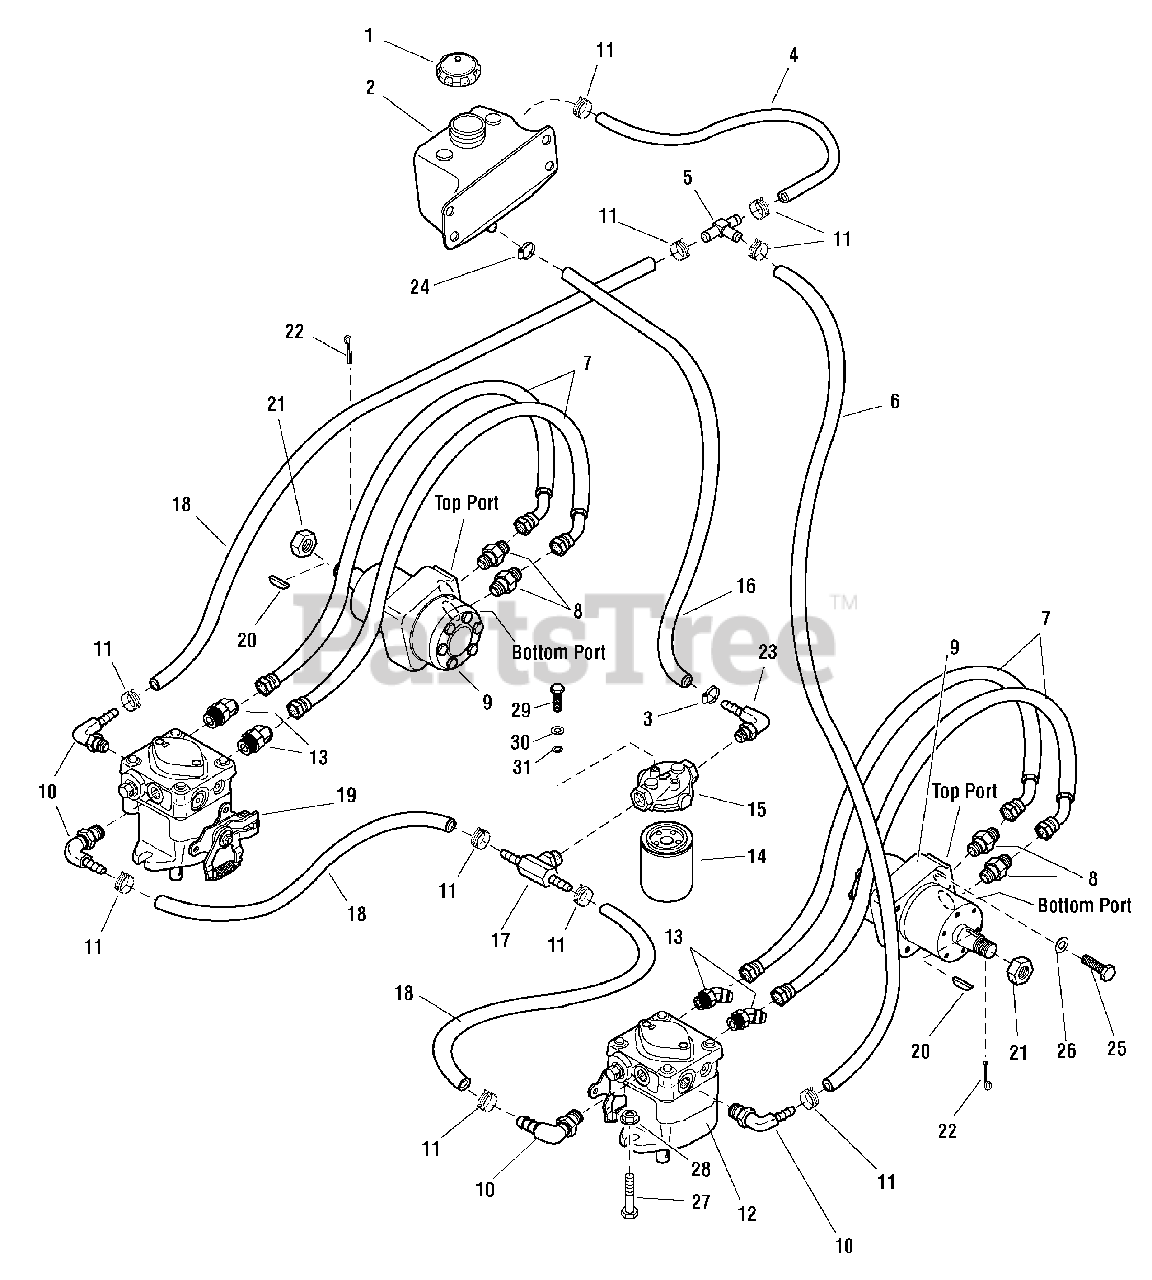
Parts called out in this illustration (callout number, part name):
1	CAP
2	HYDRAULIC TANK
3	CLAMP, #10 HOSE STAINLESS
4	HOSE, 3/8 X 8.50" LONG
5	TEE FITTING
6	HOSE, 3/8 X 27" LONG
7	25.5" HOSE ASSEMBLY
8	FITTING, ADAPTER
9	WHEEL MOTOR
10	FITTING, 90 DEG. O-RING
11	CLAMP, HOSE
12	PE, 10CC HYDRAULIC PUMP - LH
13	FITTING, ADAPTER
14	FILTER
15	FILTER HEAD
16	HOSE, 5/8 X 12.5" LONG
17	FITTING, TEE
18	HOSE, 3/8 X 7.5 " LONG
19	PE, 10CC HYDRAULIC PUMP - RH
20	KEY
21	NUT, CASTLE
22	PIN, COTTER, 1/8 X 1-1/4
23	ADAPTER, 90 DEG, 9/16-5/8 BARB
24	CLAMP, HOSE 7/8
25	BOLT, 3/8-16 X 1" GD5 YZ
26	WASHER, 3/8" SPLIT LOCK
27	BOLT, 3/8-16 X 1-1/4" GD5
28	NUT, 3/8-16 HEX SERRATED FLANGE
29	BOLT, 1/4-20 X 3/4" GD5 YZ
30	WASHER, 1/4 SAE (5025154)
31	WASHER, 1/4" LOCK
